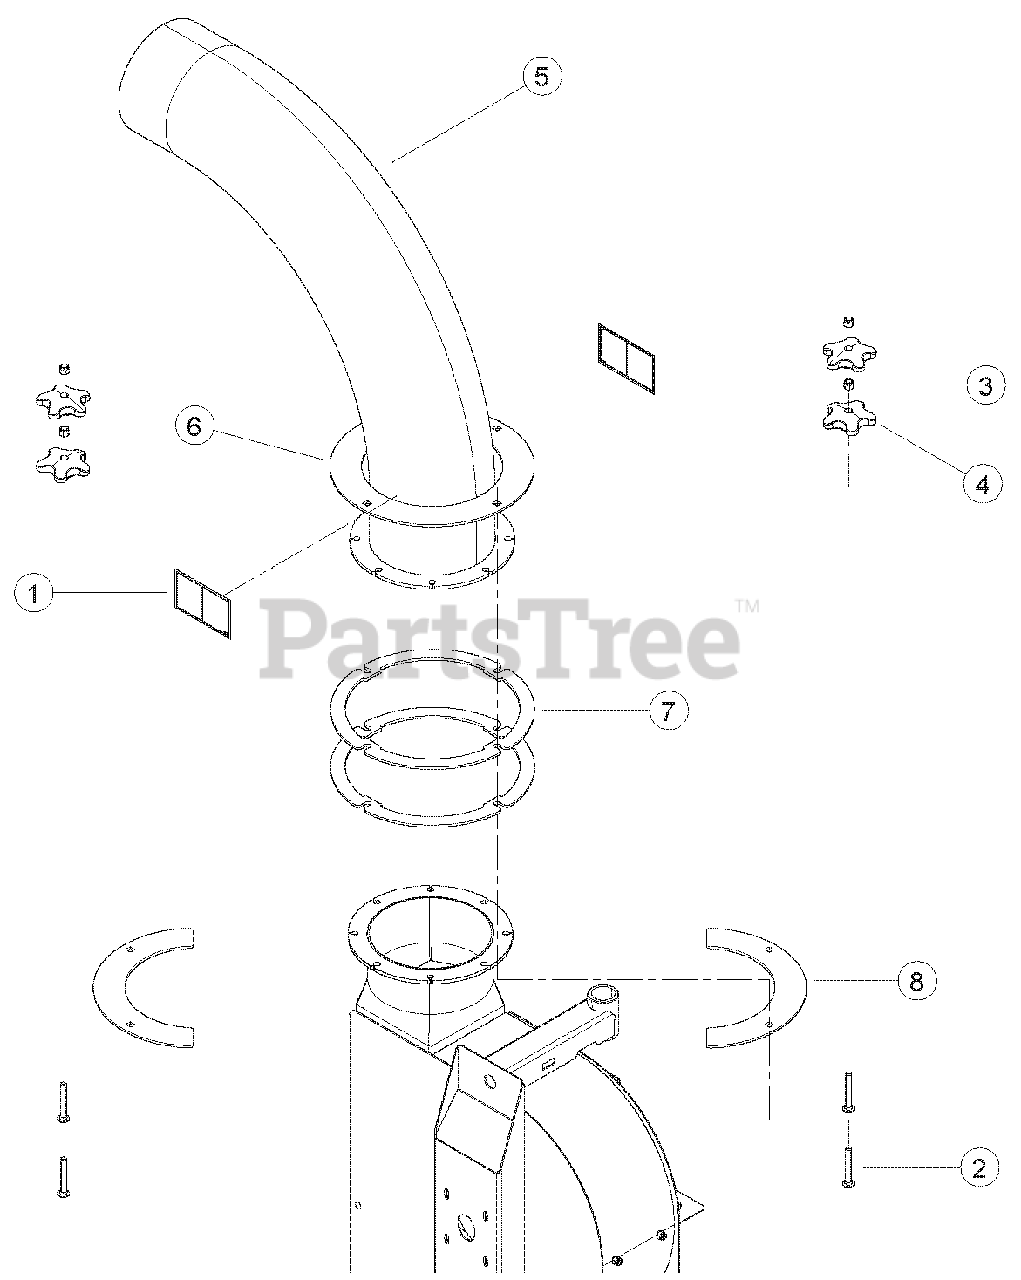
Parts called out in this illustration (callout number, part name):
1	DECAL, DISCHARGE ISO
2	BOLT, 3/8 X 2-3/4 CRG GR5 ZP
3	NUT, 3/8 NYLOCK ZP
4	KNOB, 3/8 INSERT
5	WELDMENT, DISCHARGE
6	SPACER, DL DISCHARGE
7	RING, DL DISCHARGE
8	RING, DL DISCHARGE
